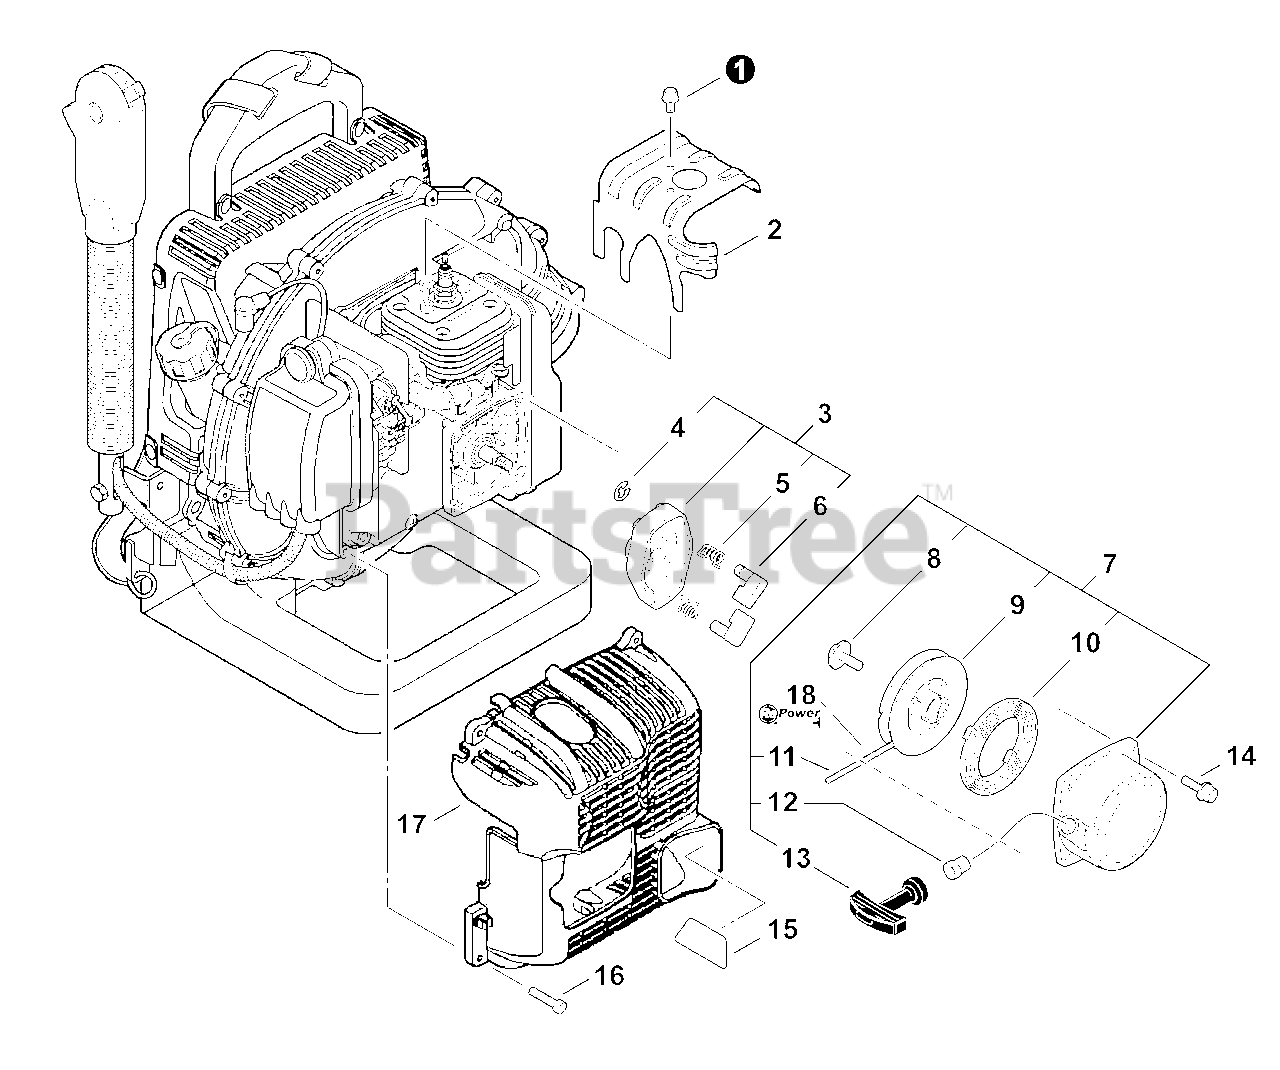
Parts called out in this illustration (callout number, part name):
1	BOLT 5×8
2	COVER, CYLINDER
3	PAWL ASSY, STARTER
4	E-RING 4
5	SPRING, RETURN
6	PAWL, STARTER
7	STARTER ASSY
8	SCREW
9	REEL, ROPE
10	SPRING, SPIRAL
11	ROPE, STARTER
12	GUIDE, ROPE
13	GRIP, STARTER
14	BOLT 5×18
15	DEFLECTOR, HEAT
16	SCREW TAPPING 5×20
17	COVER, ENGINE
18	BULK STARTER ROPE - Ø 3.0 MM×61 M
